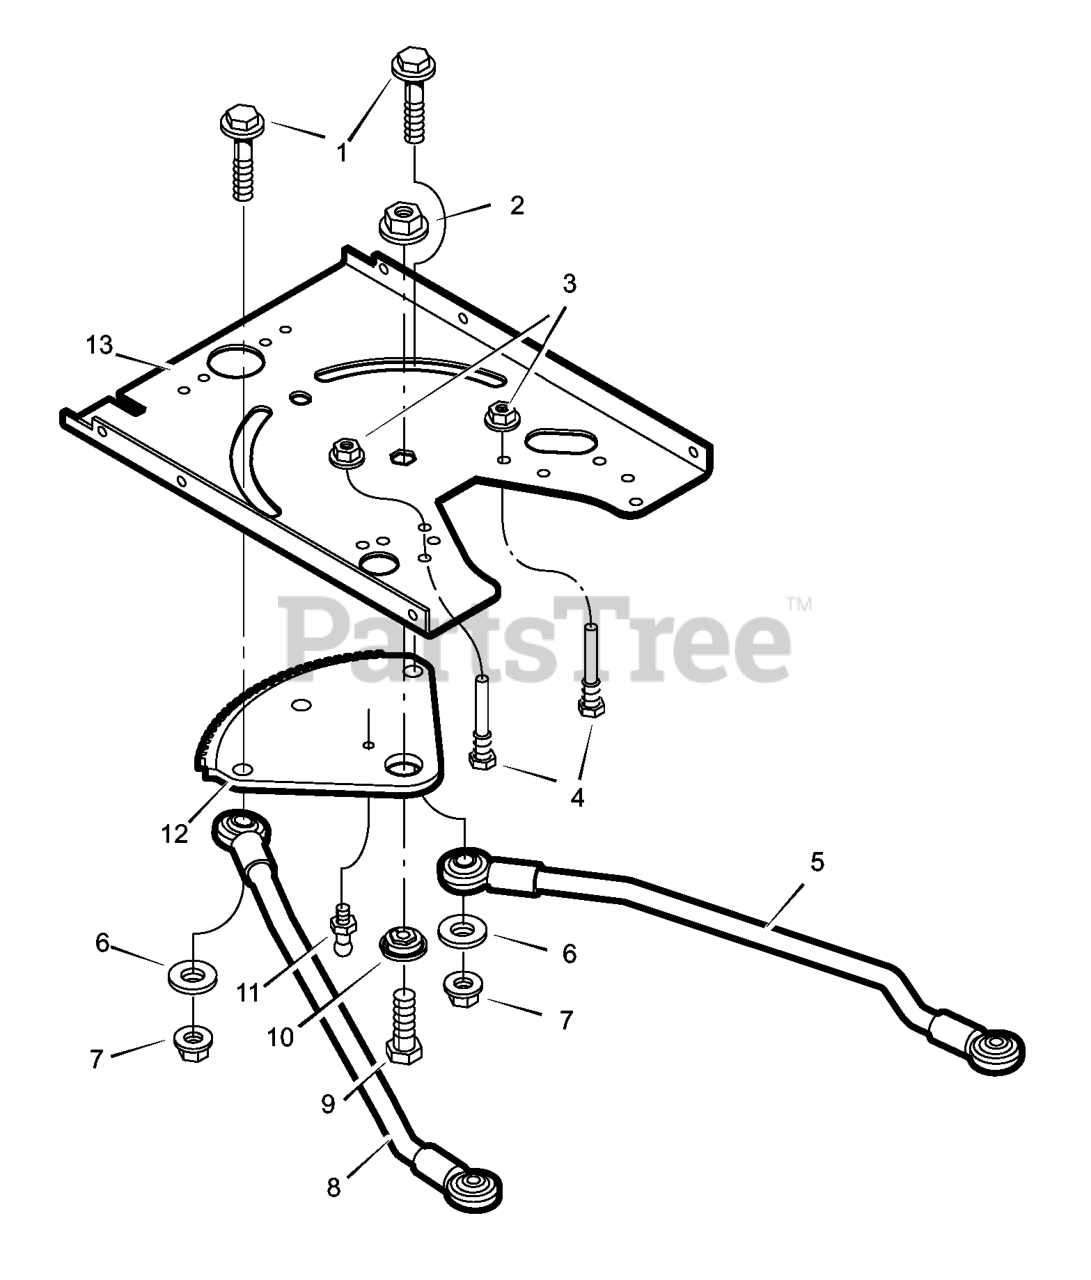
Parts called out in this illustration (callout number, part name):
1	Bolt, Shoulder
2	Nut, Lock
3	Nut, Flange
4	Guide, Screw
5	Link, Left Drag
7	Nut, Flange
8	Link, Right Drag
9	CAPSCREW, Hex Head, 5/16-18 x 1
10	Bearing, Sector Gear
11	Fitting, Lub
12	Gear, Sector
13	Plate, Steering
